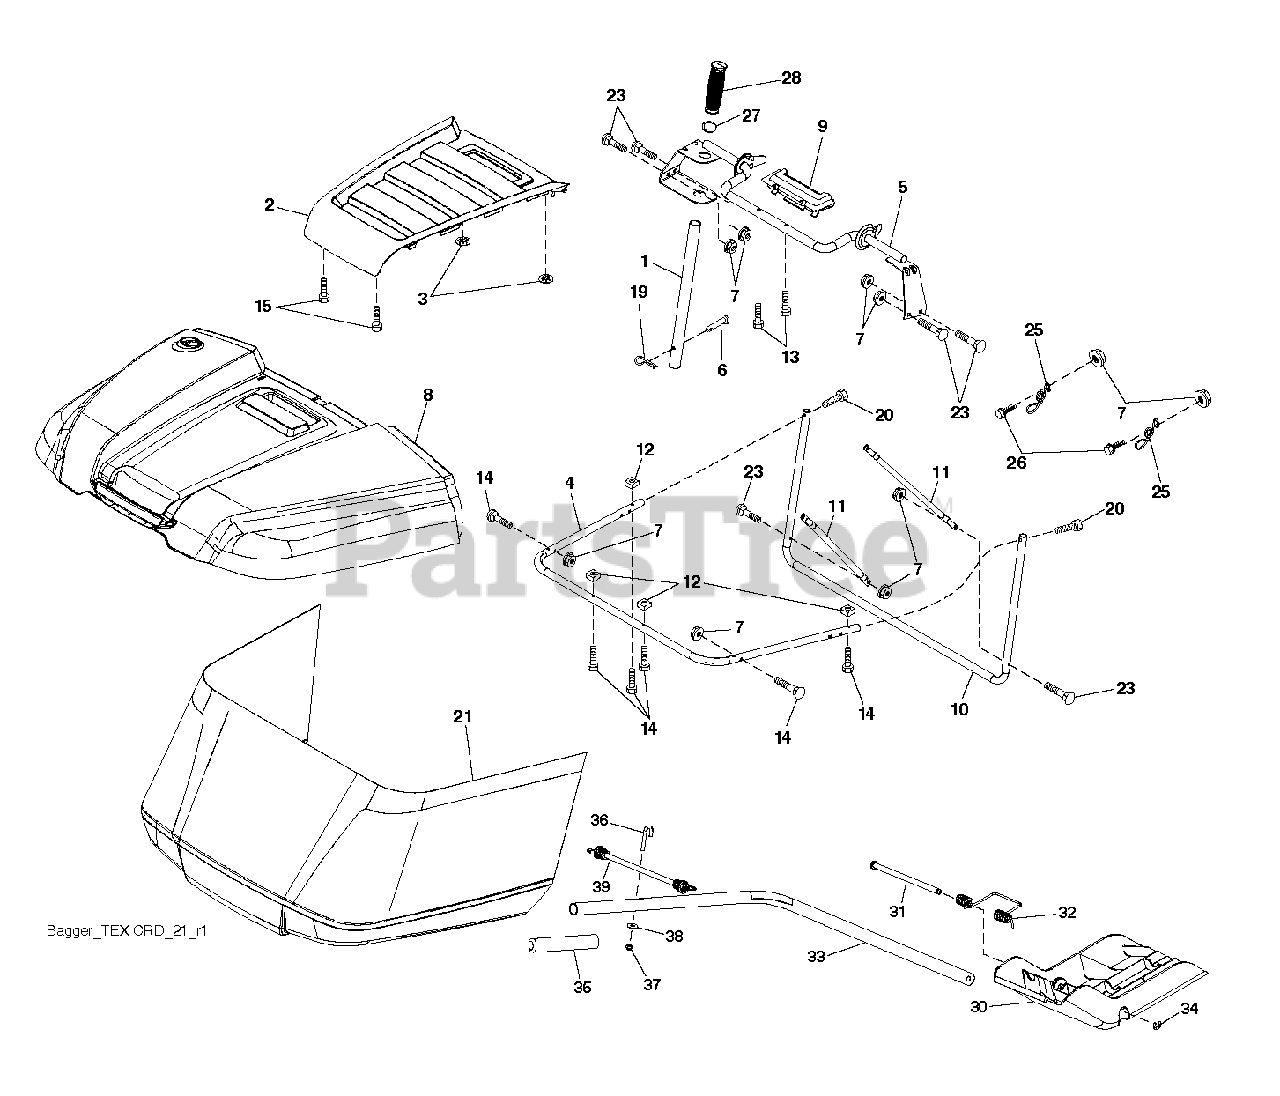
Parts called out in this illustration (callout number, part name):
1	TUBE.HANDLE.BAGGER.CRD/SRD.BLA
2	APPLIQUE.TOP.BAG.SRD.ORANGE
3	NUT.PUSH.156
4	SUBASM.TOP.TUBE.TEX.CRD
5	FRAME.ASM.TOP.BAGGER.SRD
6	RIVET,DRILLED
7	NUT T
8	BAGGER.TOP.SRD.APPLIQUE
9	INSERT.HANDLE.BAGGER.(2 2)
10	FRAME FRAME.FRONT.TEX.CRD
11	BRACE BRACE SIDE TUBE
12	NUT.SQUARE.1/4
13	SCREW.1/4X1.150.HXWSH
14	BOLT.SHOULDER.HX.WSH.1/4X1.150
15	SCREW,#8.FLAT.HEAD.DRILL.TIP
19	PIN.COTTER.5/16.BOW TI
20	SCREW.HEXCAP.1/4-20X1.375(2 2)
21	BAG SUBASM. TEX CRD GEN 2 HUSQ
25	SPRING.LATCH.BAGGER.SRD
26	SCREW HEX CRT
27	RB GROMMET.RUBBER.SRD
28	GRIP.HANDLE.BLACK
30	PLUG PLUG
31	PIN PIN.HINGE
32	SPRING SPRING DOUBLE TORSION
33	SHAFT SHAFT TEX CRD MULCH PLU
34	E-RING.5/16"
35	GRIP GRIP MULCH PLUG HAND
37	Plug Support Bagger CRD
39	BUBGEE BUBGEE TEX CRD
